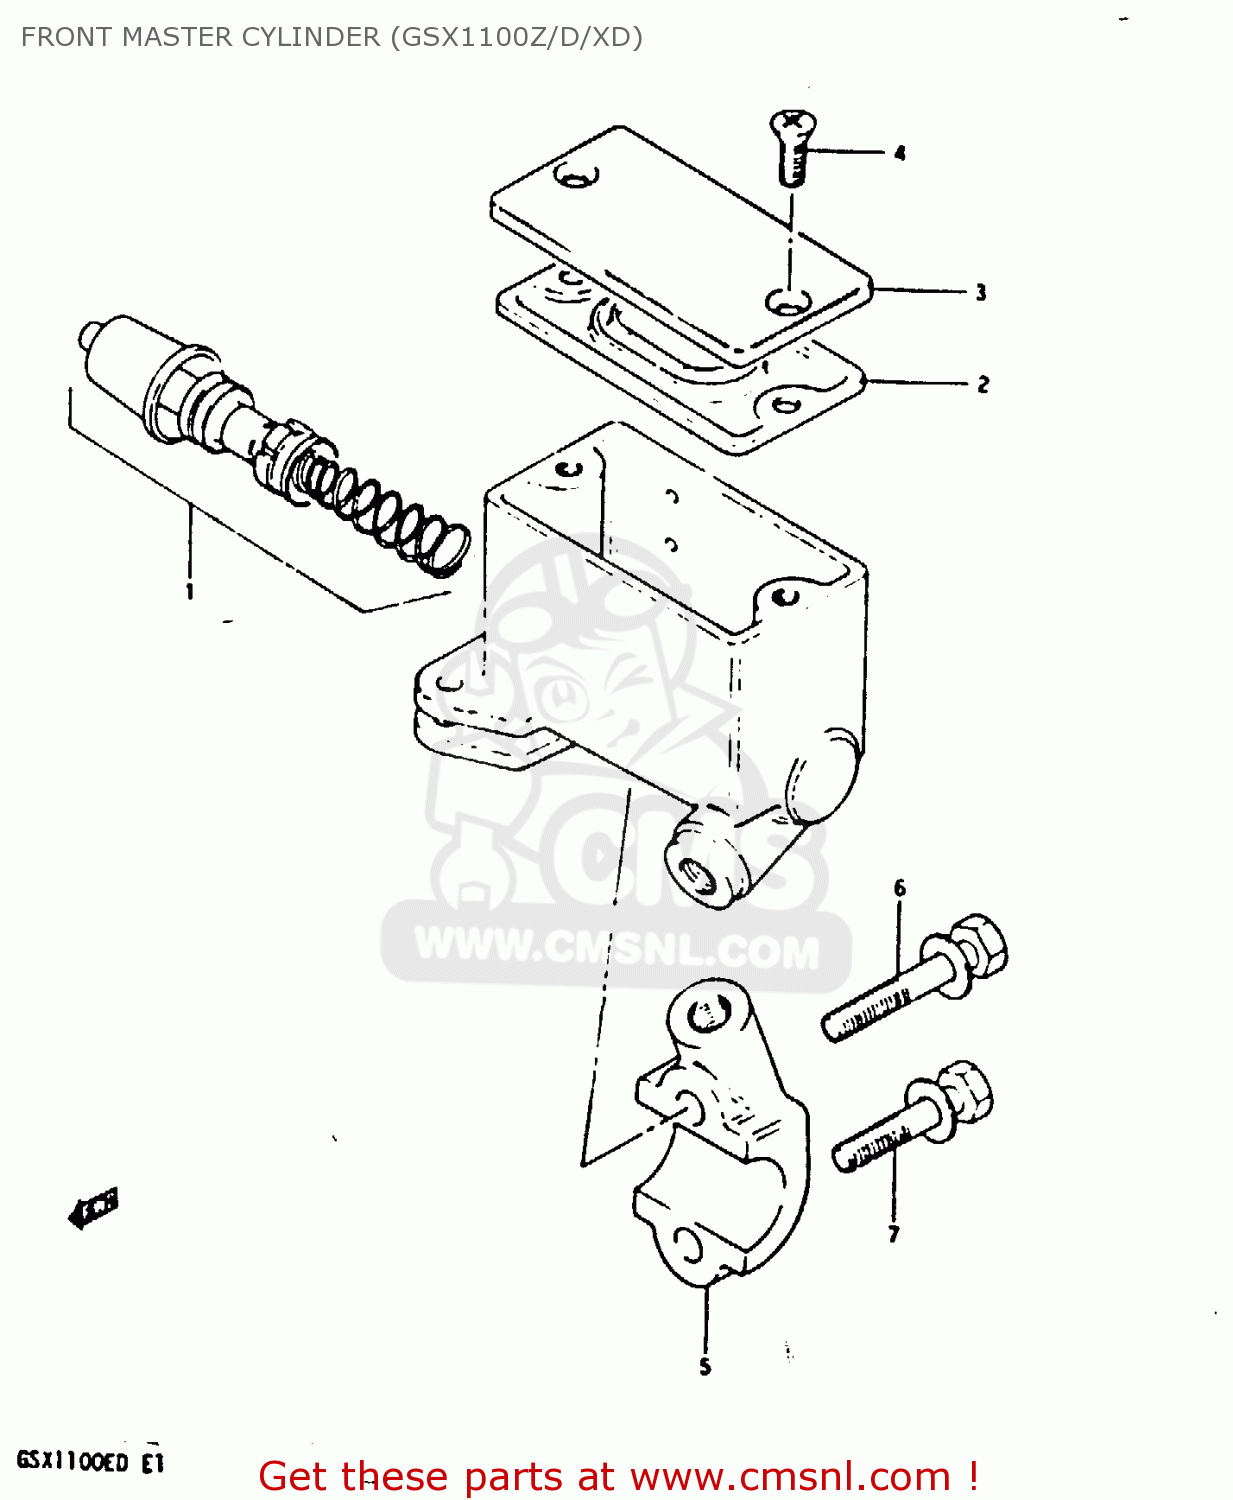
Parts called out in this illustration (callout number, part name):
1	PISTON & CUP SET
2	DIAPHRAGM,MASTER CYLINDER
3	CAP
4	SCREW
5	HOLDER
6	BOLT,MASTER CYLINDER H
7	BOLT,MASTER CYLINDER H
